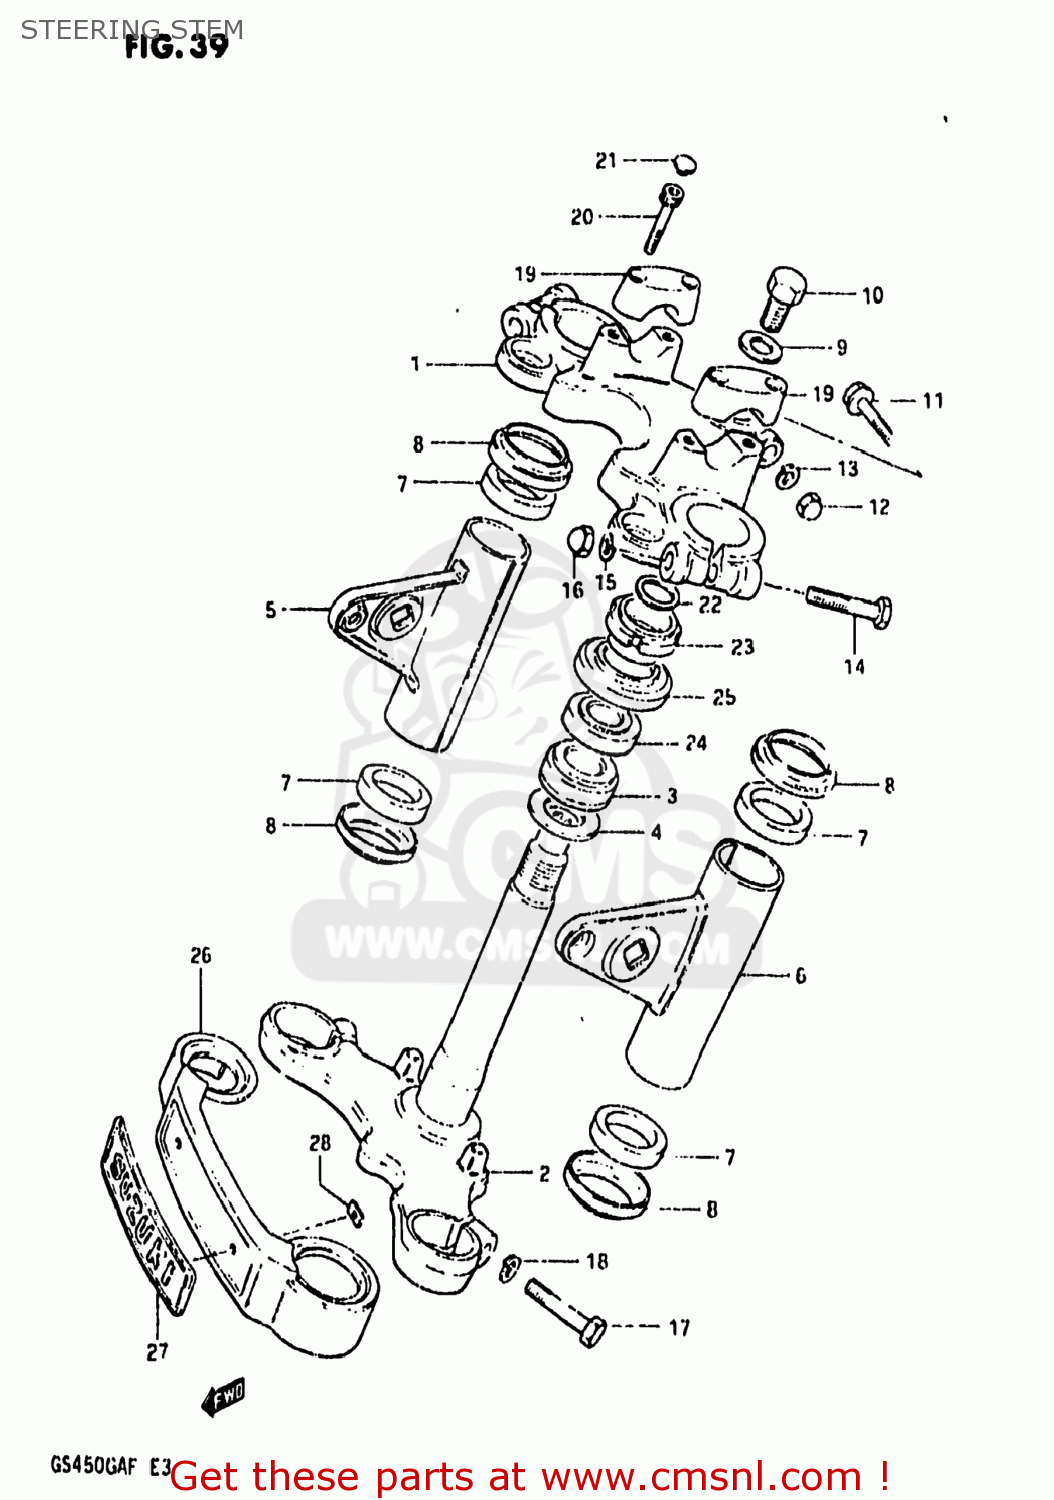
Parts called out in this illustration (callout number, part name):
1	HEAD,STEERING STEM
2	STEM,STEERING
3	BEARING
4	WASHER,THRUST
5	BRACKET,HEADLAMP,RIGHT
6	BRACKET,HEADLAMP,LEFT
7	CUSHION,HEADLAMP BRACKET
8	CAP,HEADLAMP BRACKET
9	WASHER (12.5X27X1.6)
10	BOLT(12X20)
11	BOLT, UPPER
12	NUT,M8X1.25X12
13	WASHER,LOCK,8.
14	BOLT
15	LOCK WASHER
16	NUT
17	BOLT
18	LOCK WASHER
19	HOLDER,HANDLEBAR(BLACK)
20	BOLT, REAR (8X30)
21	CAP(OD:14.5)
22	WASHER(18.5X24X1)
23	NUT,STEERING STEM
24	TAPER,ROLLER BEARING
25	DUST SEAL,STEERING UPR
26	COVER,FRONT FORK
27	EMBLEM,FR FORK COVER
28	NUT
